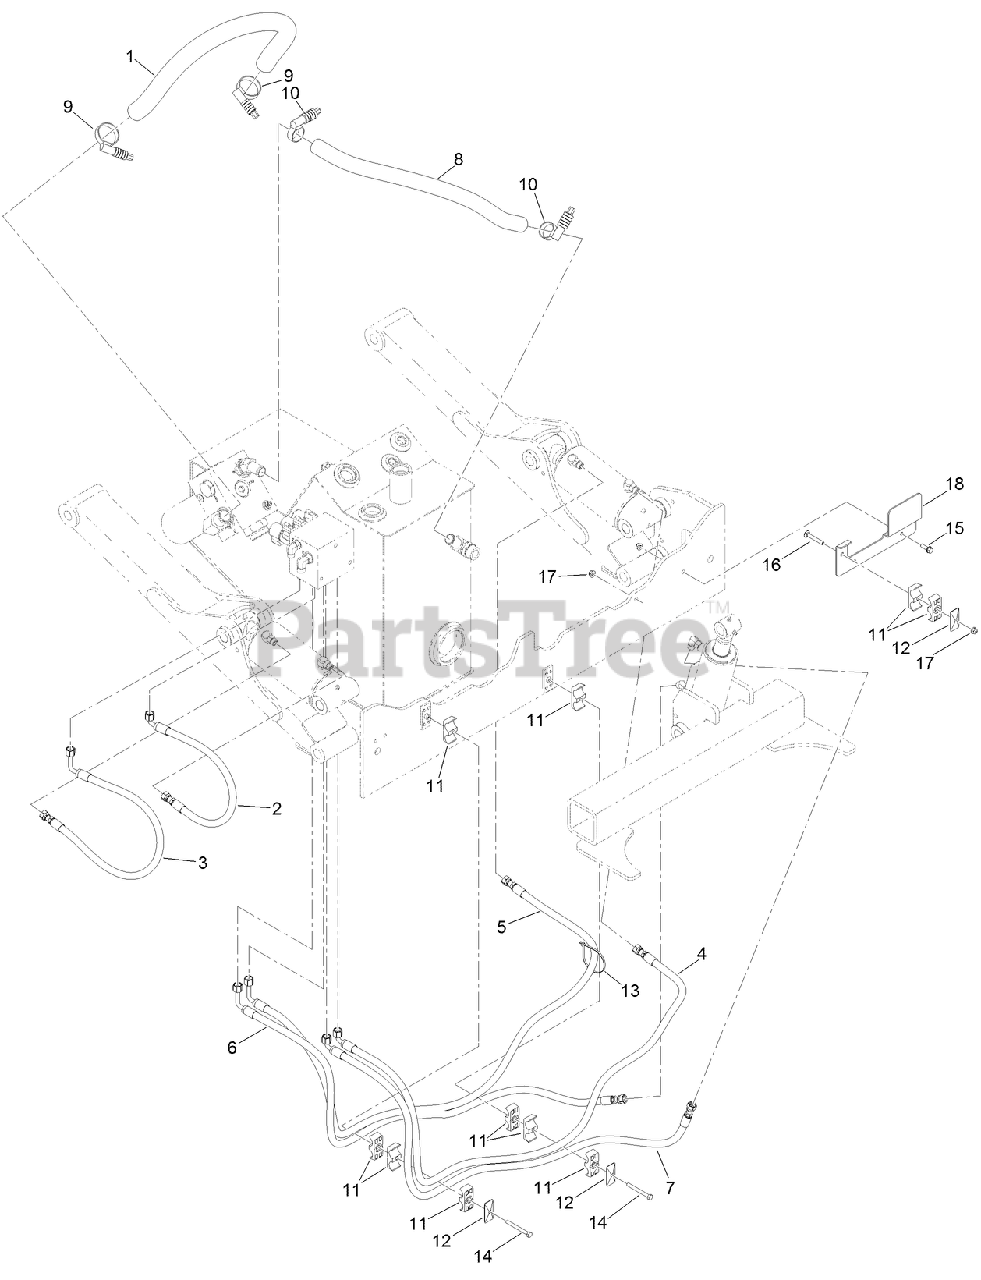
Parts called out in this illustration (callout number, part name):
1	HOSE-HYDRAULIC
2	HOSE ASM-HYD
3	HOSE ASM-HYD
4	HOSE ASM-HYD
5	HOSE ASM-HYD
6	HOSE ASM-HYD
7	HOSE ASM-HYD
8	HOSE-HYDRAULIC
9	CLAMP-TORQUE, CONSTANT
10	CLAMP-TORQUE, CONSTANT
11	CLAMP-TUBE
12	PLATE-COVER
13	TIE-CABLE
14	SCREW-HH
15	SCREW-HHF
16	BOLT-CARR
17	NUT-HF, NI
18	GUARD-HOSE
